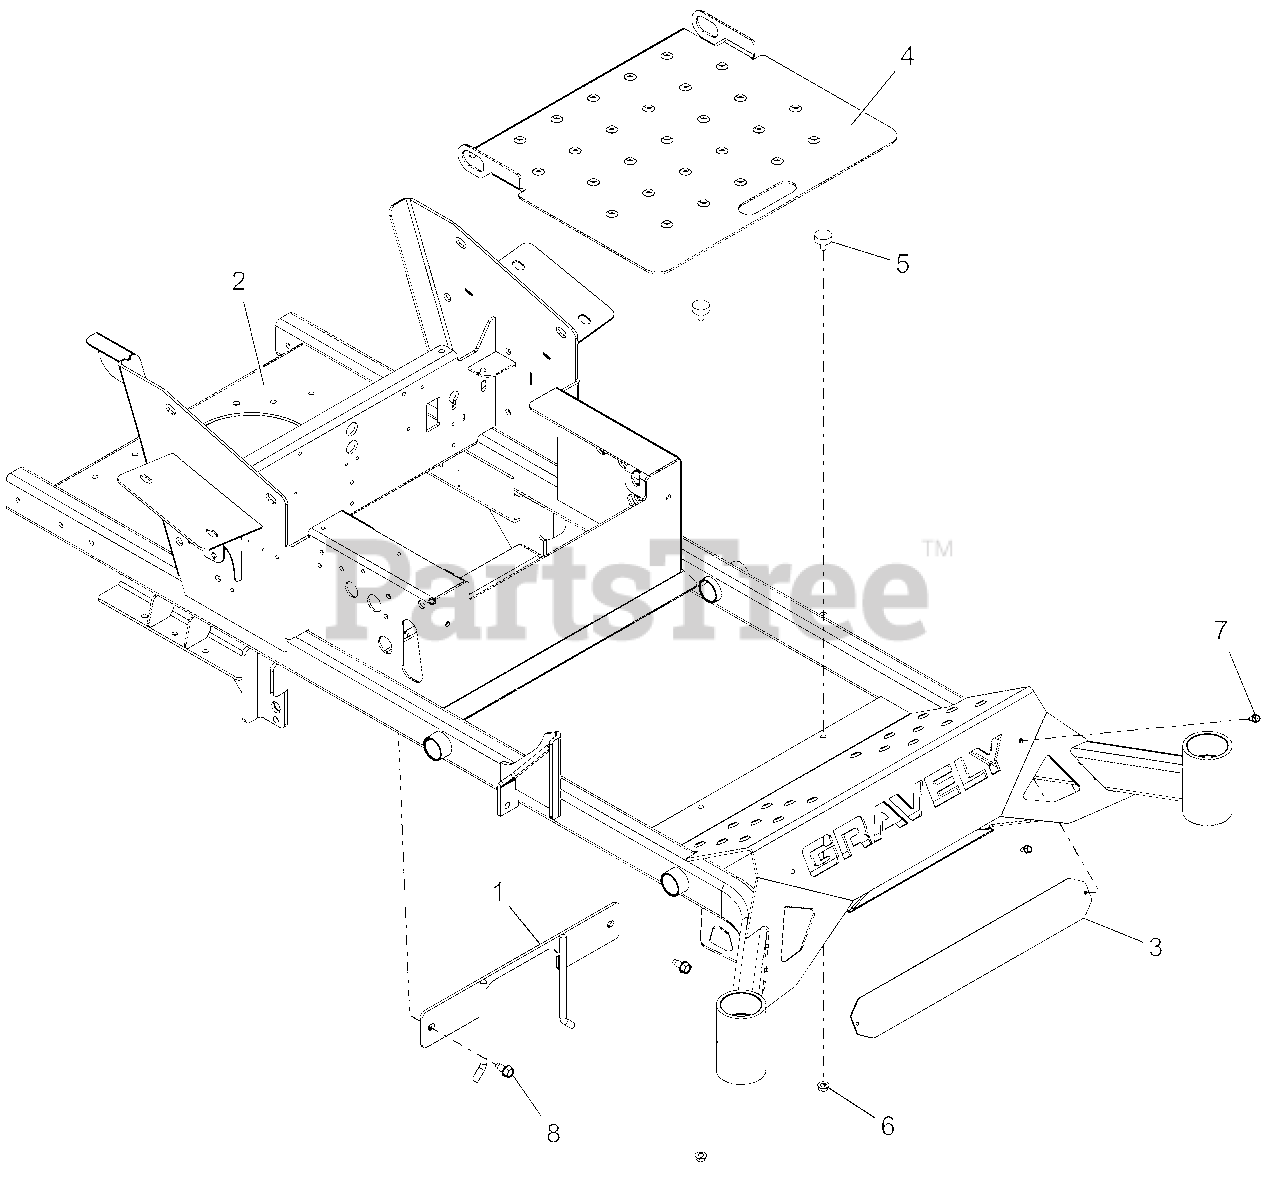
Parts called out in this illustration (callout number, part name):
1	PTO BELT FINGER WLDMT - BLK
2	PT/100 60" FRAME W/SAFETY DECL
3	BUMPER LOGO BACKING PLATE -BLK
4	PT/100 FOOT PLT W/SAFETY DECAL
5	BUMPER, RUBBER
6	@NUT-SPNLK-FLG .312-18 YWZC
7	SCR-TAP .25-20X.50 HWH TR YWZ
8	@SCR-TAP .38-16X.75 HWH TR YWZ
